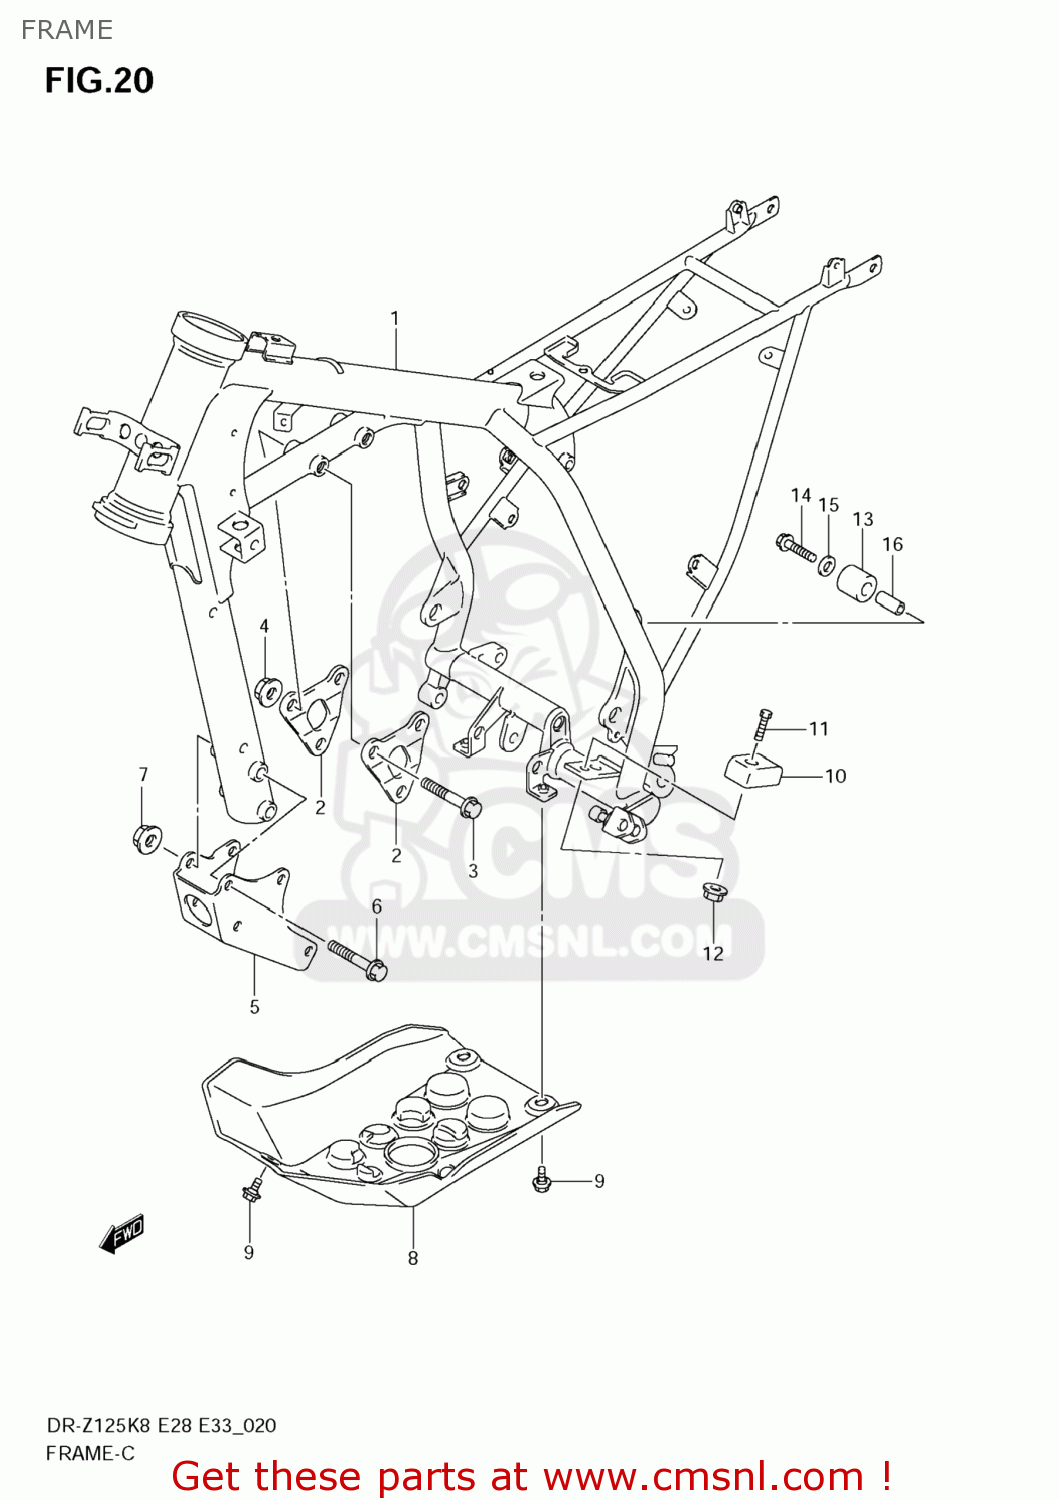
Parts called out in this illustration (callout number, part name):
1	FRAME
2	PLATE,ENG MTG UPR
3	BOLT(8X53)
4	NUT
5	PLATE,ENG MTG LWR
6	BOLT(8X65)
7	NUT
8	PROTECTOR,ENGINE
9	BOLT
10	GUIDE,CH LENGTH CONTROL LWR
11	BOLT(6X16)
12	NUT
13	ROLLER,CHAIN CONTROL UPR
14	BOLT(8X38)
15	WASHER
16	SPACER(8.6X12.2X26.5)
